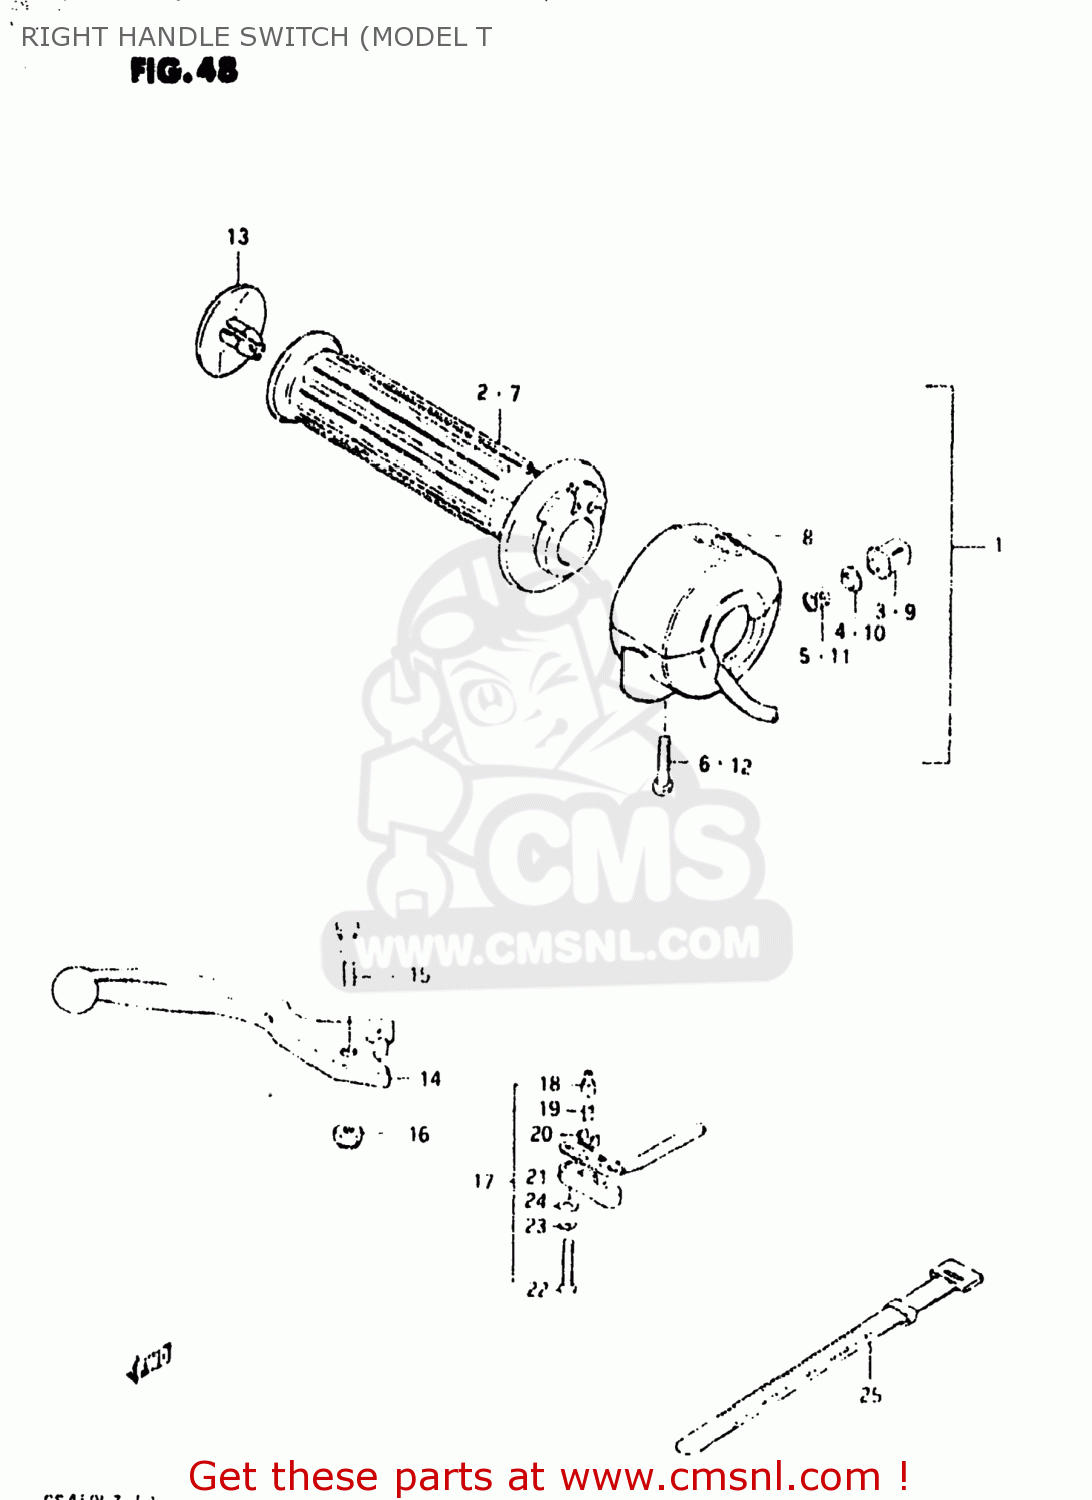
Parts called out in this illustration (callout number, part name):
1	CASE ASSEMBLY,THROTTLE
2	GRIP,THROTTLE
3	BUTTON,HORN
4	CONTACT
5	SPRING
6	SCREW
7	GRIP,THROTTLE
8	CASE ASSEMBLY,THROTTLE
9	BUTTON,HORN
10	CONTACT
11	SPRING
12	SCREW
13	CAP,GRIP END
14	LEVER,BRAKE
15	BOLT
16	NUT 6MM
17	SWITCH ASSEMBLY
18	HOLDER
19	SPRING
20	PLATE
21	COVER,FR BK TERMINAL BASE
22	SCREW
23	LOCK WASHER
24	WASHER
25	CLAMP(L:120)
